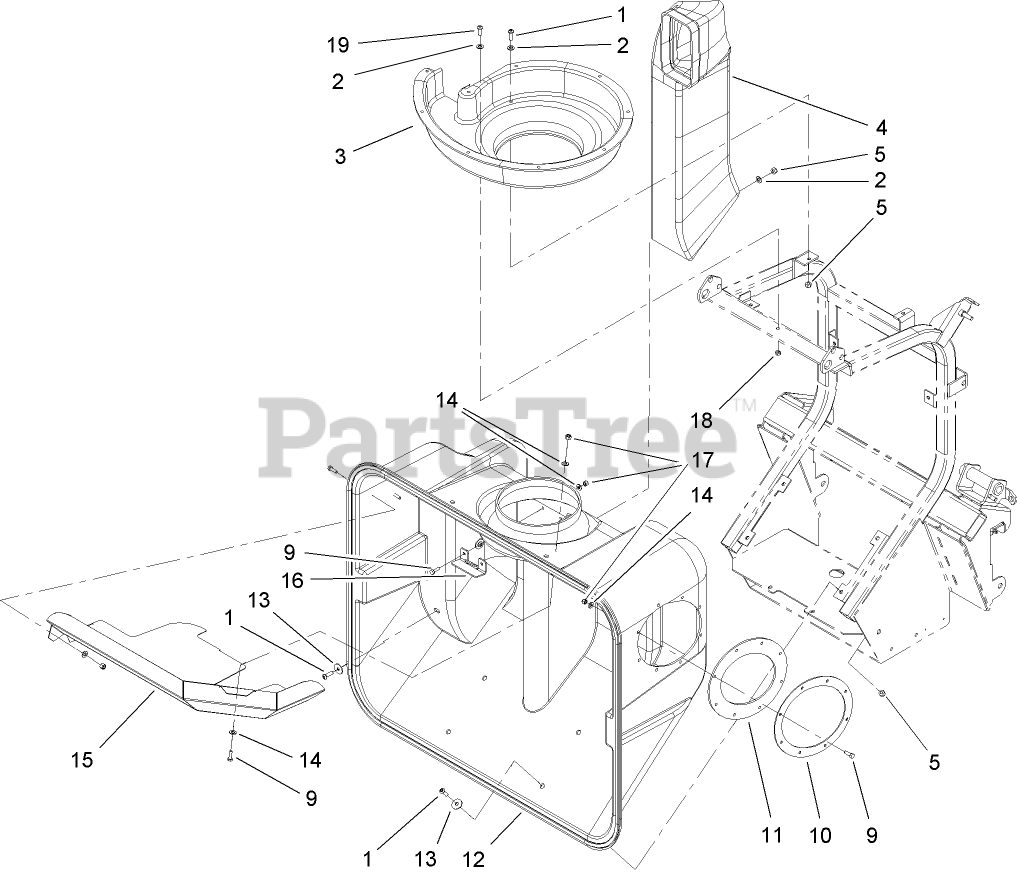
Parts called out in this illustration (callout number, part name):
1	SCREW-HSBH
2	WASHER-PLAIN
3	SCROLL-BOTTOM
4	TUBE-EXHAUST
5	NUT-LOCK, NI
9	SCREW-HH
10	PLATE-SEAL
11	SEAL-RUBBER
12	HOPPER-FRONT
13	WASHER-FLAT
14	WASHER-FLAT
15	SCREEN ASM
16	BRACKET-SCREEN, LOWER
17	NUT-LOCK, NI
18	NUT-LOCK, NI
19	SCREW-HSBH
